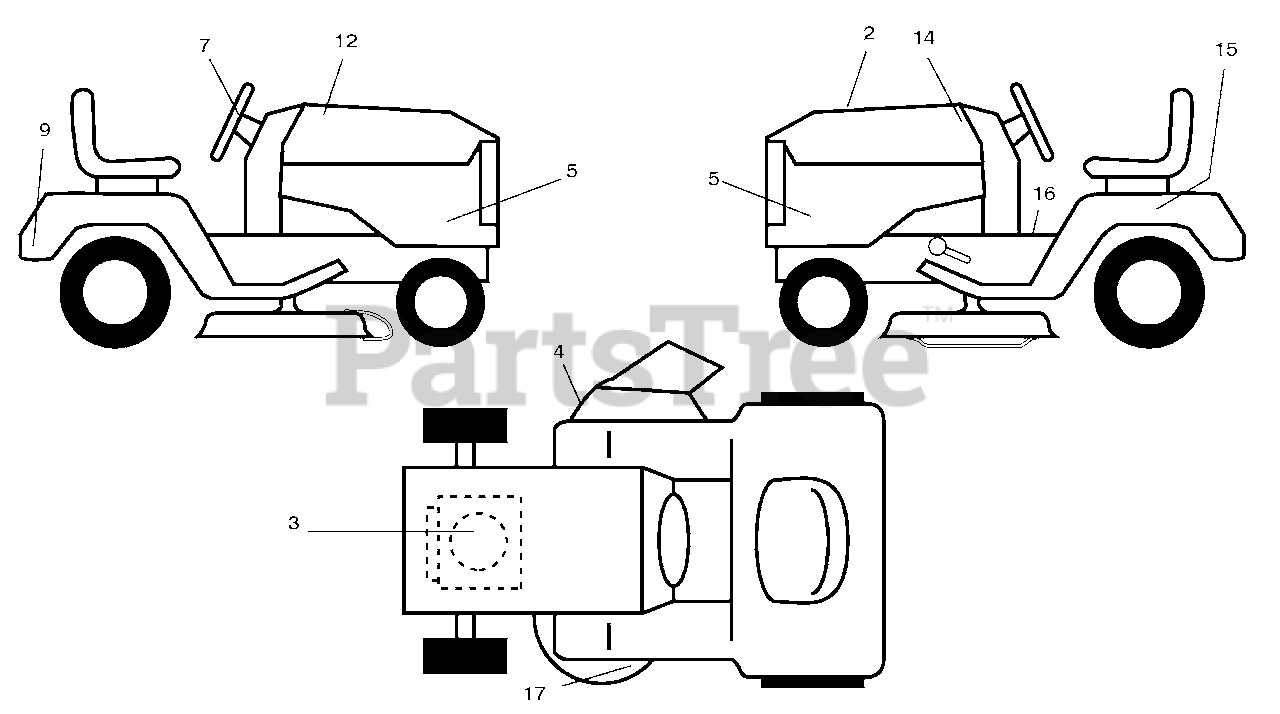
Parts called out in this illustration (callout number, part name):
2	Decal, Replacement
3	Decal, Engine HP
4	Decal, Warning
5	Decal, SDPNL
7	Decal, Ins Str Wh
9	Decal, Fender
12	Decal, Hood RH
14	Decal, Hood LH
15	Decal, Caution, Battery
16	Decal, Fender Warning Eng/Fr
17	Decal, V-Belt Sch.
17	Decal, Handle Lft Height Adj.
17	Manual, Operator's E&F
17	Manual, Parts E&F
